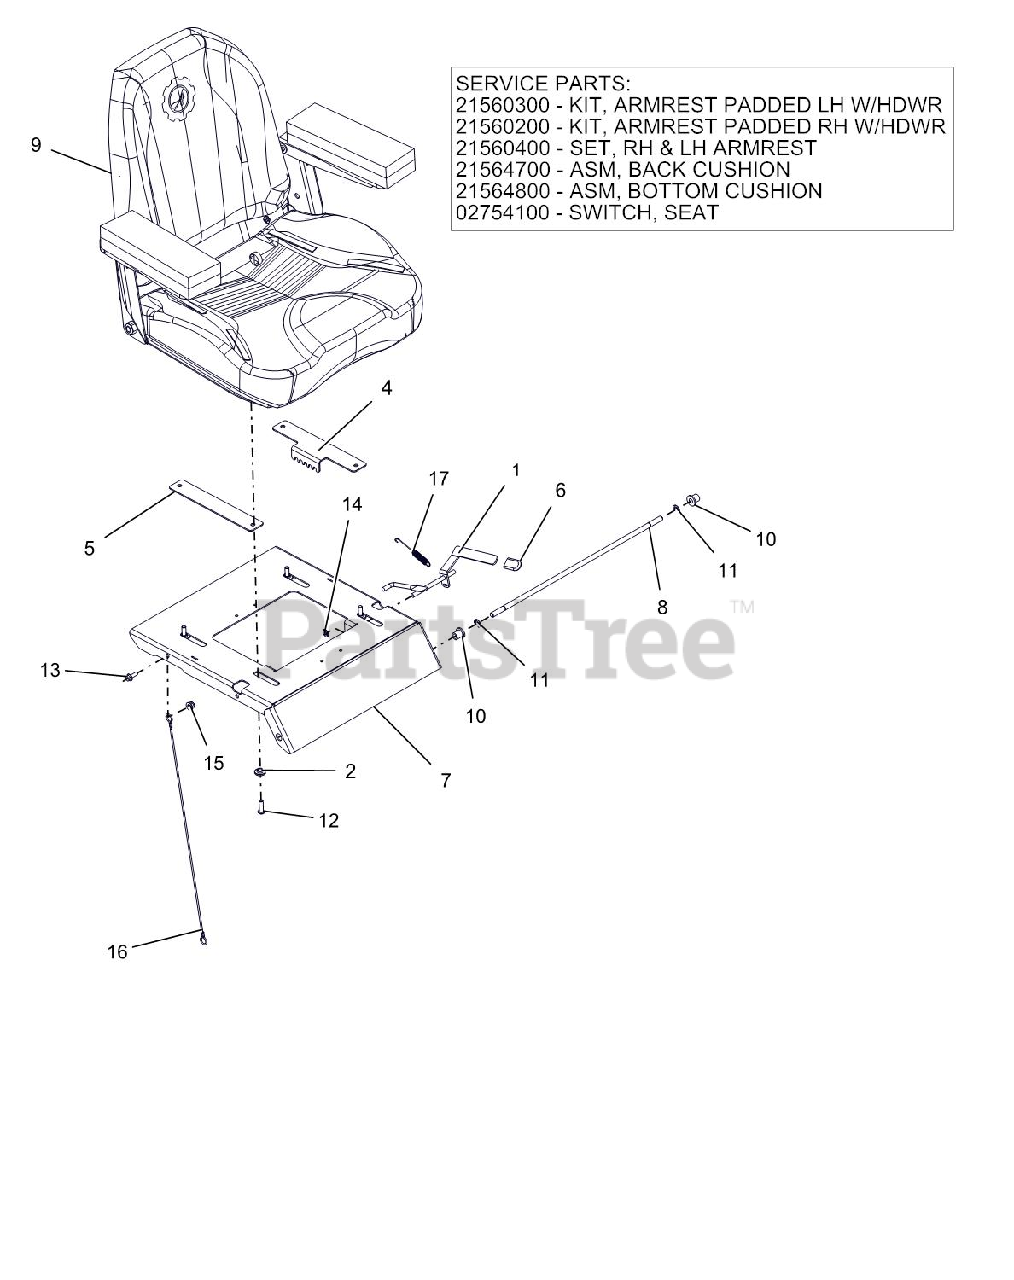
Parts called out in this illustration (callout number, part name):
1	WLDMT, ADJUSTABLE SEAT LATCH
2	BSHG, FLG .325X.499X.26X.88
4	PLATE, ADJUSTABLE SEAT TRACK
5	PLATE, ADJUSTABLE SEAT SLIDE
6	GRIP, SEAT LEVER, GREY
7	PLATE, SEAT
8	ROD, SEAT PIVOT
9	SWITCH- SNAP MTG N.O.
9	PAD,LH ARMREST LIGHT GREY SOFT
9	PAD, RH ARMREST LIGHT GREY
9	SET,RH & LH ARMREST -LTGREY
9	SEAT, IKON XL
9	ASM, BACK CUSHION-ARIENS X
9	ASM, BOTTOM CUSHION-ARIENS X
10	BSHG-FLG .38X.580X.667X.750
11	RG-RTNG-EXT .375X.035 TYP E
12	SCR-SKH .31-18X1.0 BTNHD YWZC
13	BLT,HEX-FLG .25-20X.75 G5 BFP
14	NUT-PUSH .312
15	@NUT-LK-NYL-FLG .31-18 YWZC
16	LANYARD, SEAT CABLE .093X19.5
17	SG-TENS .043X.44X3.31 WLD 5.8
